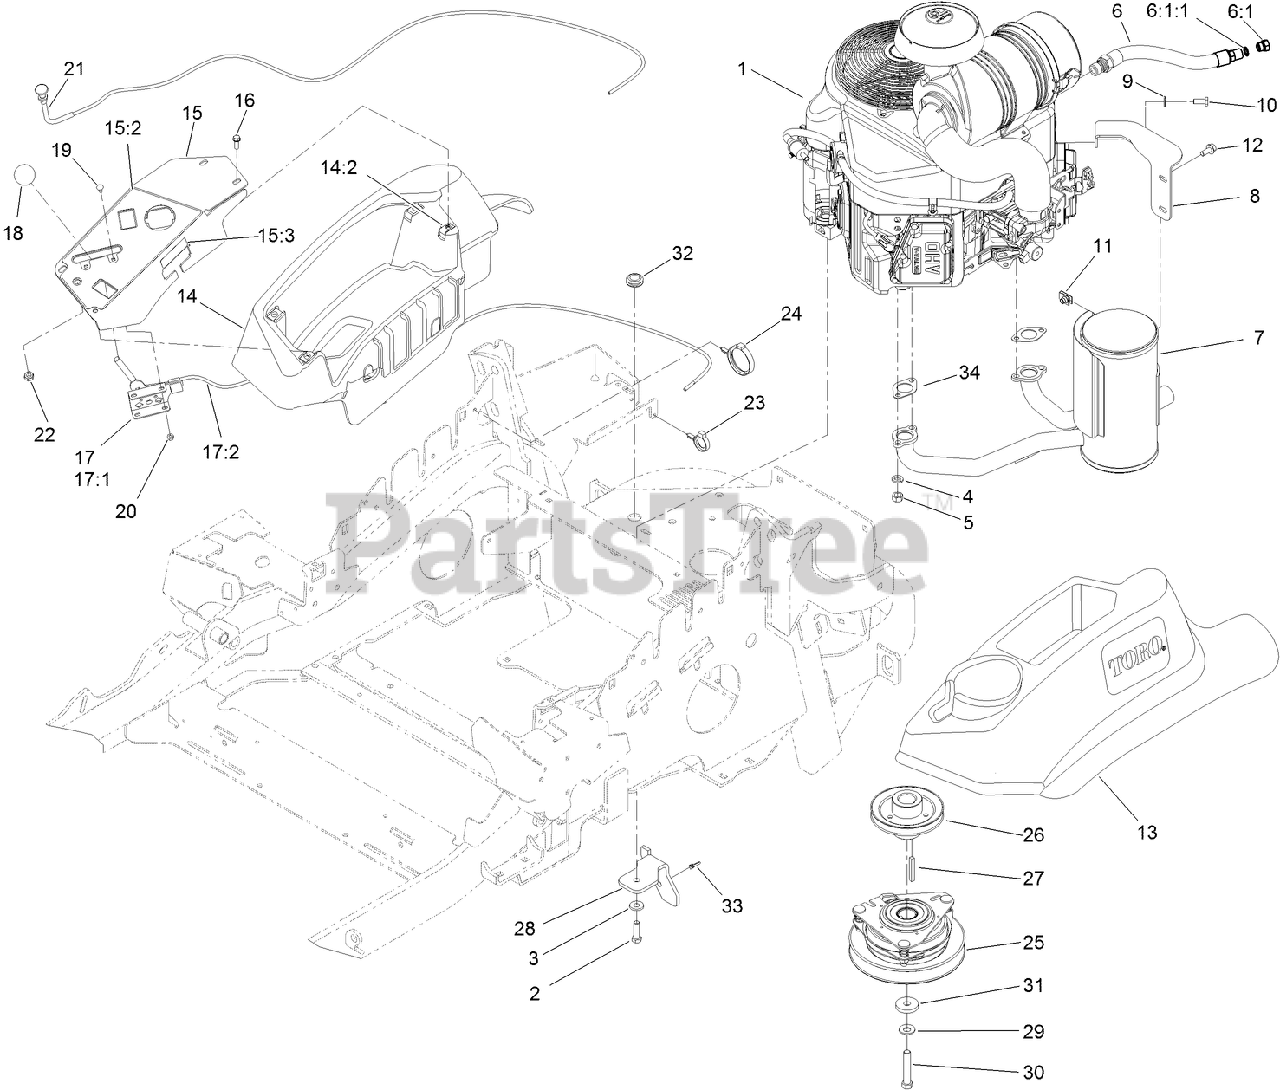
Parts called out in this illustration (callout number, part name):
2	SCREW-HH
3	WASHER-BELLEVILLE
4	WASHER-LOCK
6	ENGINE OIL DRAIN HOSE ASM
6:1	PLUG-HH
6:1:1	O-RING
7	MUFFLER
8	BRACKET-MUFFLER
9	WASHER-SPRING
10	SCREW-HH
11	NUT-U
12	SCREW-HHF
13	CONSOLE-LH
14	RH CONSOLE ASM
15	CONTROL PANEL ASM
15:2	DECAL-PANEL, CONTROL
15:3	DECAL-FUSES
16	SCREW-HWH
17	THROTTLE CONTROL ASM
17:1	LEVER-THROTTLE
17:2	CABLE-THROTTLE
18	KNOB-BALL
19	BOLT-CARR
20	NUT-LOCK, NI
21	CONTROL-CHOKE
22	NUT-HJ
23	CLAMP-HOSE
24	CLAMP-HARNESS
25	CLUTCH
26	PULLEY-ENGINE
27	KEY-SQUARE
28	BRACKET-STOP, CLUTCH
29	WASHER-SPRING
30	SCREW-HH
31	WASHER
32	GROMMET
33	TIE-CABLE
34	GASKET-EXHAUST
